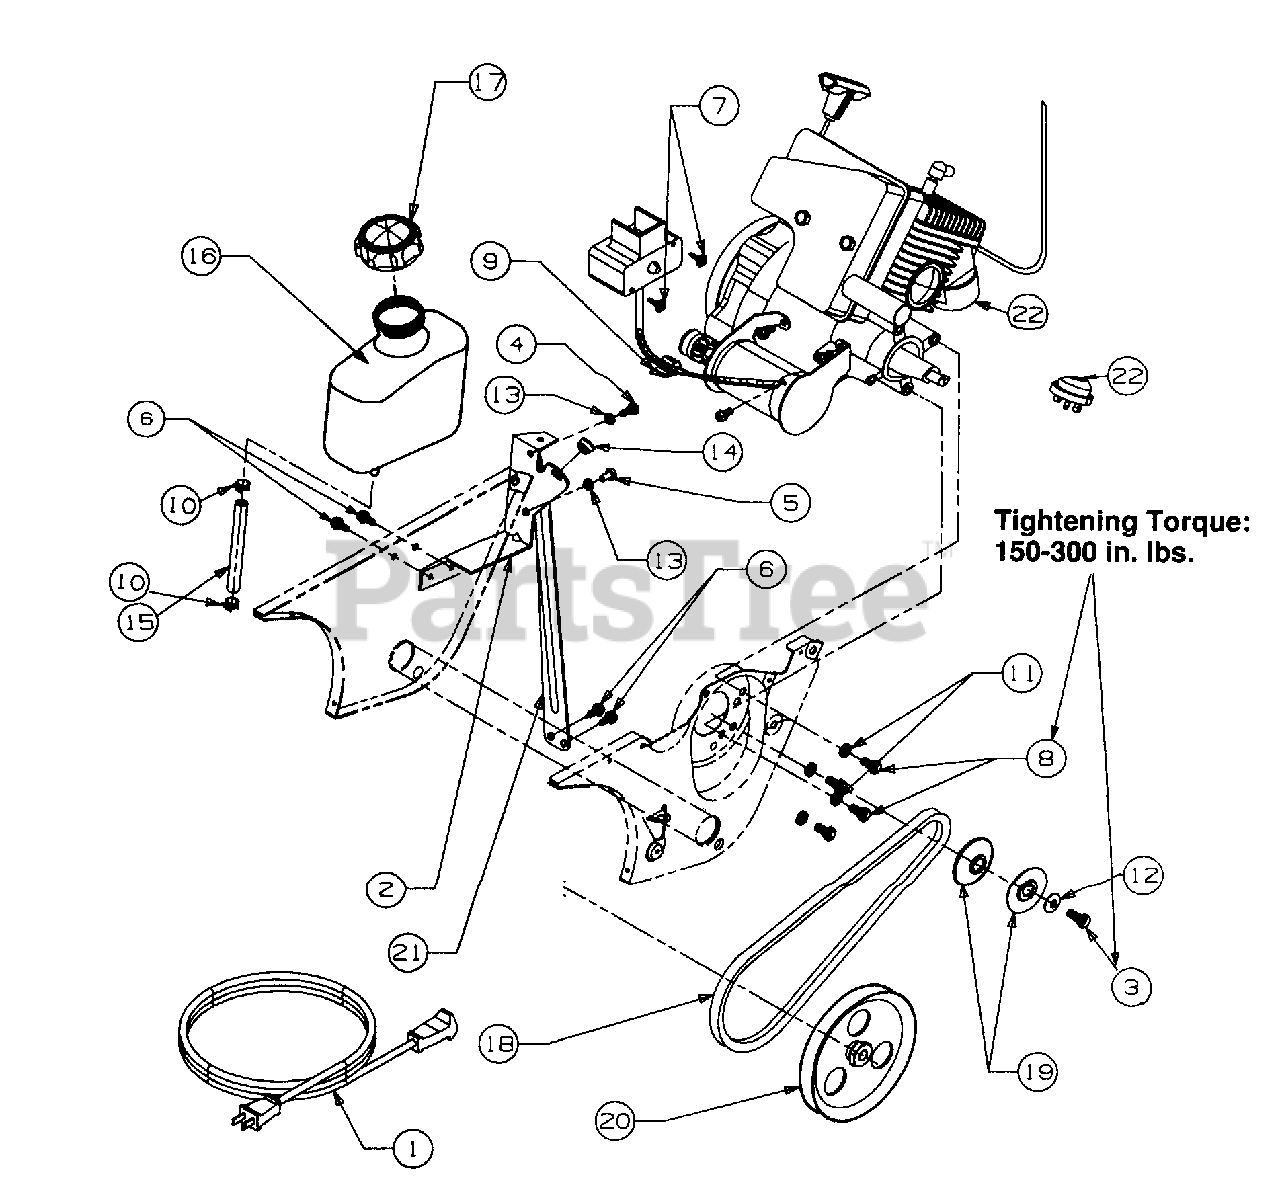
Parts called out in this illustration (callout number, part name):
1	Cord - Extension 110V3M 2 Prong
2	Bracket - Support Fuel Tank
3	Screw - Hex Cap
4	Screw - Hex Cap
5	Screw - Hex
6	Screw - Washer
7	Screw - Hex
8	Screw - Hex Cap
9	Clamp - Mounting
10	Clamp - Hose
11	Washer - Lock
12	Washer - Bell
13	Washer - Lock
14	Bushing - Plastic
15	Hose - Fuel Line 16"
16	Tank - Fuel 2 Qt.
17	Cap - Fuel
18	V-Belt
19	V-Pulley Half
20	Pulley
